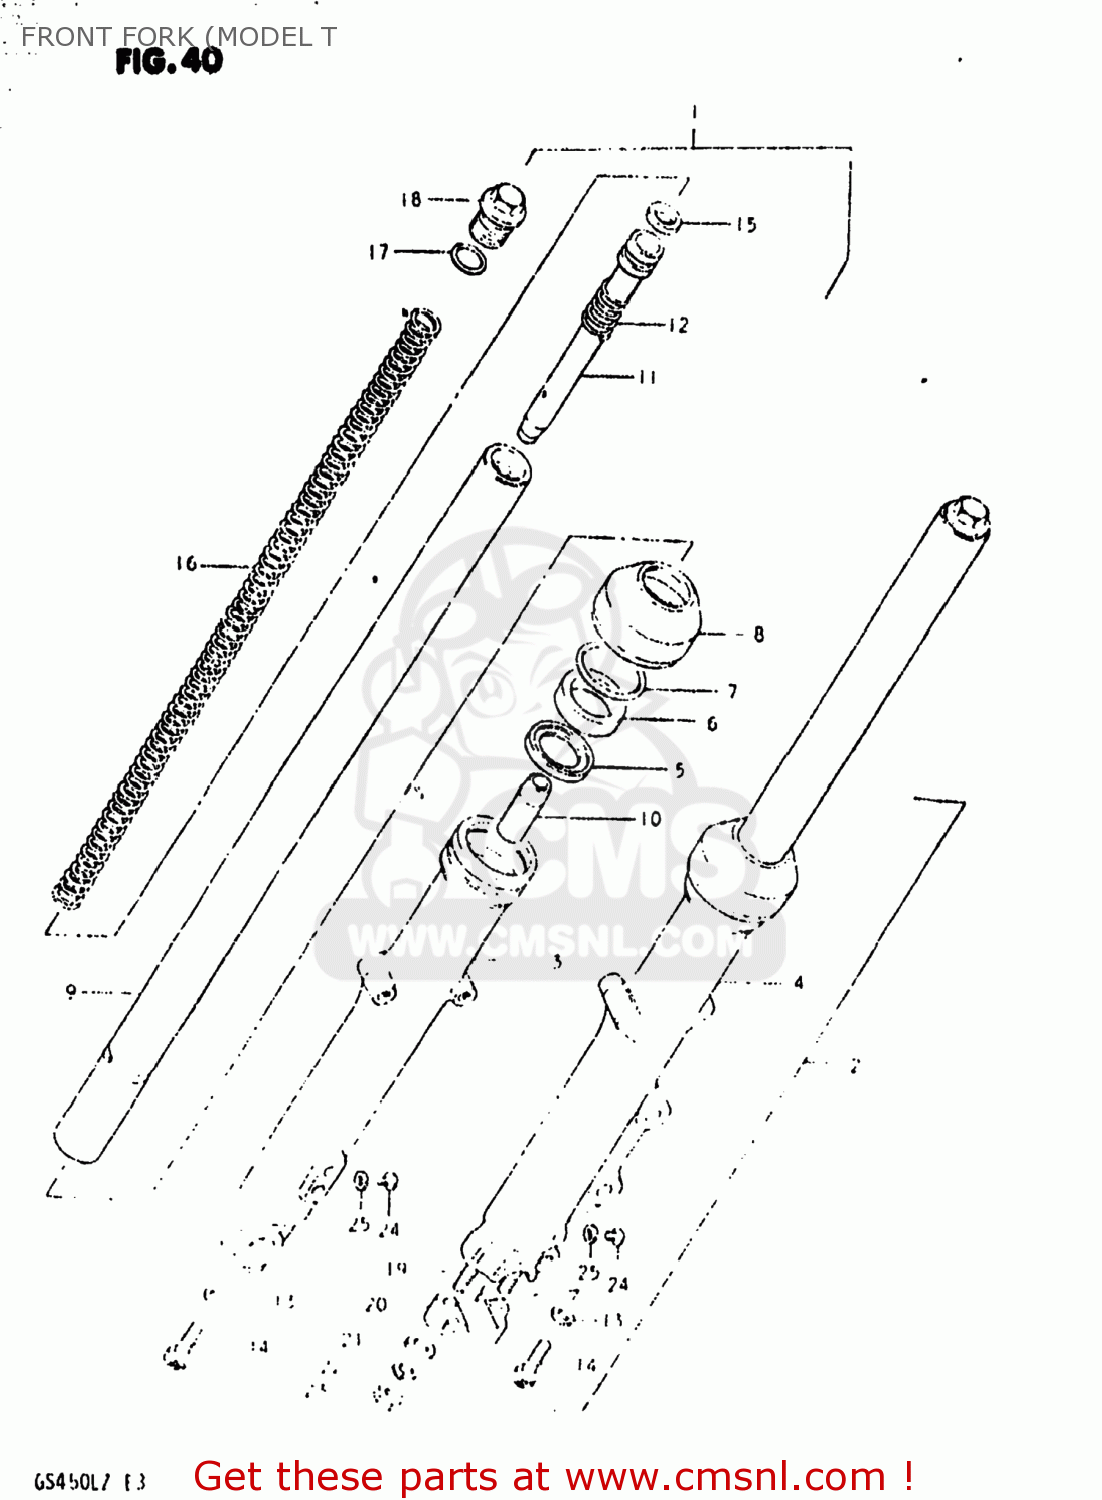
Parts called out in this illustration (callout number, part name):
1	DAMPER ASSEMBLY,RIGHT
2	DAMPER ASSEMBLY,LEFT
3	TUBE,FORK,OUTER,RIGHT
4	TUBE,FORK,LEFT,OUTER
5	SPACER,OIL SEAL
6	OIL SEAL,FRONT FORK
7	CIRCLIP,FORK OIL SEAL
8	BOOT
9	TUBE,FORK,INNER
10	PIECE,OIL LOCK
11	CYLINDER,FRONT FORK
12	SPRING,REBOUND
13	GASKET (NAS)
14	BOLT(8X27)
15	RING,PISTON
16	SPRING
17	O RING
18	BOLT
19	STUD 8X25
20	HOLDER,AXLE
21	WASHER
22	LOCK WASHER
23	NUT (8MM)
24	SCREW 4X6
25	GASKET (NAS)
